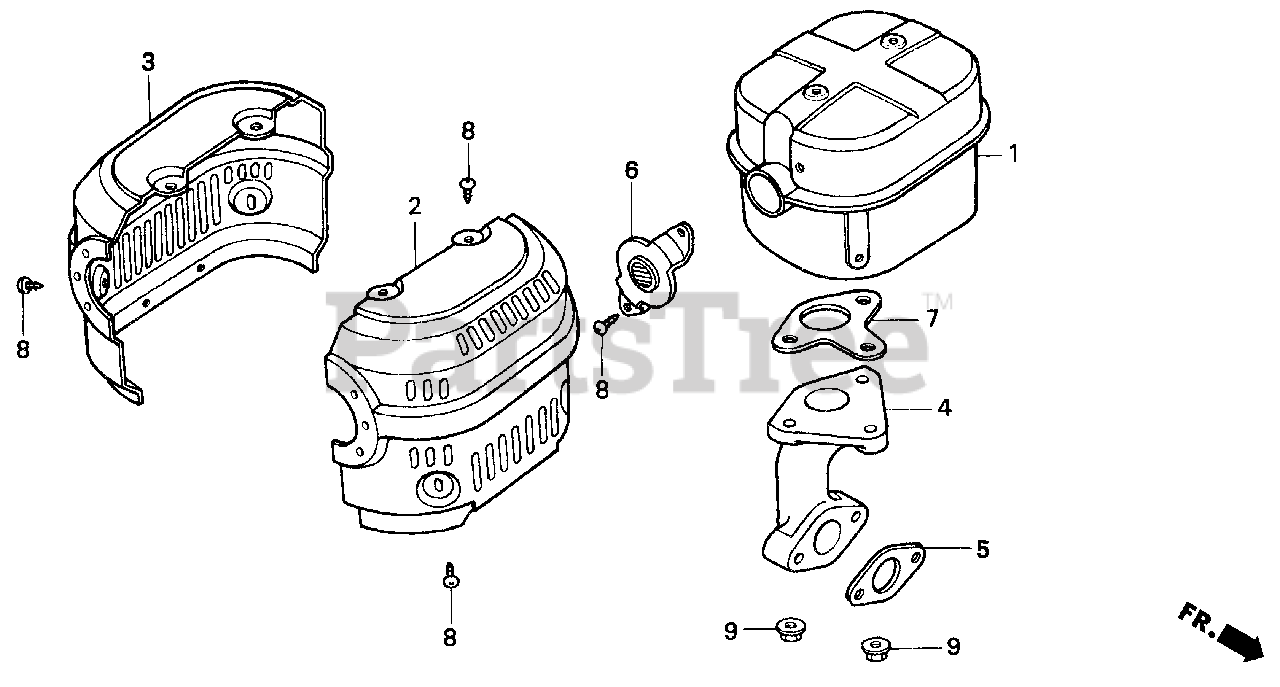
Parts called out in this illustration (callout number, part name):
1	MUFFLER
2	PROTECTOR, R. MUFFLER (ALUMINIZED)
3	PROTECTOR, L. MUFFLER (ALUMINIZED)
4	PIPE, EX.
5	GASKET, EX. PIPE
5	GASKET, EX. PIPE (WACKER)
6	FLANGE, BAFFLE
7	GASKET, MUFFLER
8	SCREW, TAPPING (5X8)
9	NUT, FLANGE (8MM)
